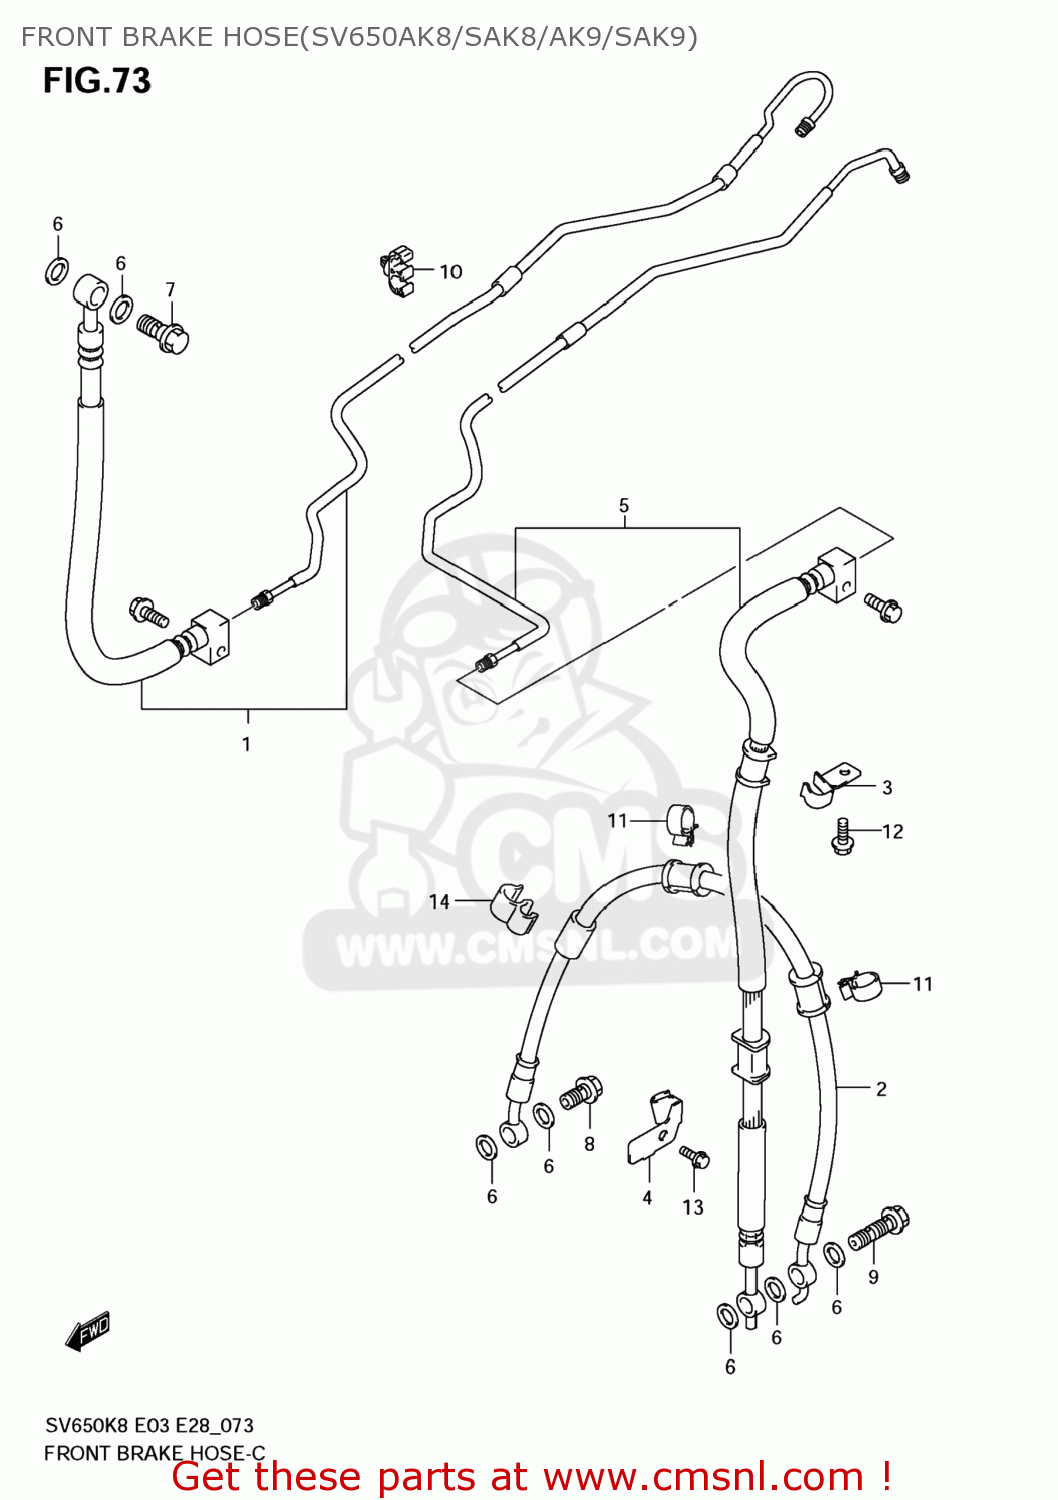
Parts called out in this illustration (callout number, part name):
1	HOSE ASSY,FR BRAKE NO.1
2	HOSE,FR BRAKE NO.2
3	CLAMP,FR BRAKE HOSE
4	CLAMP,FR BRAKE HOSE NO.2
5	HOSE ASSY,FR BRAKE NO.2
6	WASHER(10X15X1.5)
7	BOLT UNION
8	BOLT UNION
9	BOLT UNION
10	CLAMP
11	CLAMP
12	BOLT
13	BOLT
14	CLAMP
